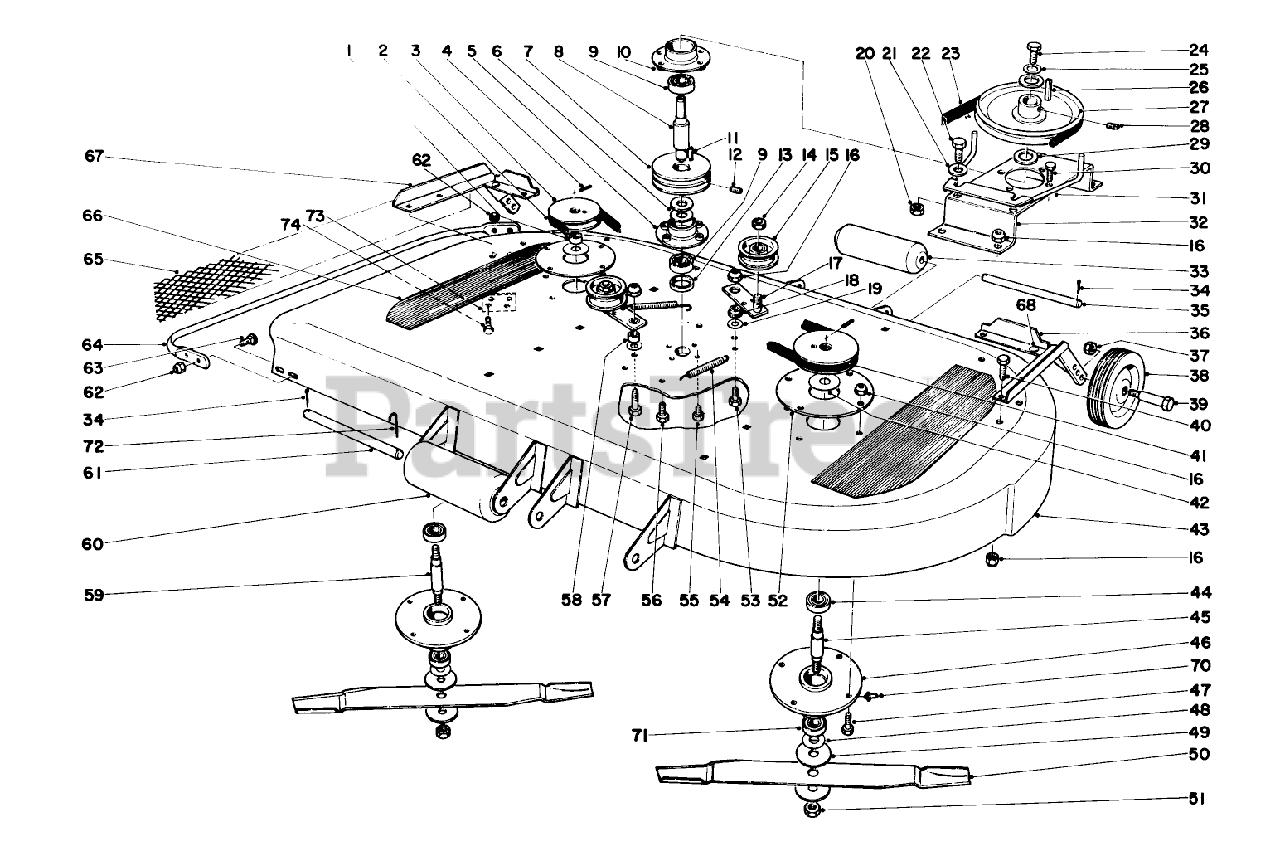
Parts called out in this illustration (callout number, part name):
1	Spacer
2	Belt
3	Pulley
4	ROLL PIN
5	Bearing Housing
6	Washer
7	Pulley
8	BLADE DRIVE SHAFT
9	Bearing
10	Bearing Housing
11	KEY-WOODRUFF
12	Set Screw
13	Spacer
14	NUT-JAM
15	PULLEY-IDLER
16	NUT-LOCK, CONE
17	Idler Arm
18	Bushing
19	WASHER-FLAT
20	NUT-LOCK, CONE
21	WASHER-FLAT
22	SCREW-HH
23	V-BELT
24	SCREW-HH
25	Washer
26	KEY-SQUARE
27	Pulley
28	Set Screw
29	Washer
30	1/4-20 X 3/8 SEMS SCR
31	Belt Guide
32	Support
33	Roller
34	PIN-COTTER
35	ROLLER SHAFT
36	Bracket
37	NUT-LOCK, CONE
38	Wheel
40	SCREW-HH
42	Washer
43	Housing
44	Bearing
45	LH BLADE SHAFT
46	MOWER SPINDLE HOUSING
47	SCREW-HH
48	WASHER
49	WASHER
50	Blade
51	NUT-LOCK, CONE
52	Washer
53	SCREW-HH
54	IDLER ARM SPRING
55	1/4-20 X 3/8 SEMS SCR
56	SCREW-HH
57	SCREW-HH
58	Spacer
59	Blade Shaft
60	Roller
61	ROLLER SHAFT
62	NUT-LOCK, CONE
63	SCREW-CARR
64	Guard
65	Mulcher
66	Foot Pad
67	Bracket
68	Plug Button
70	FITTING-GREASE
71	.6693 RP BALL BEARING
72	Retainer Roller
73	Bracket Blade Guard
74	SCREW-HH
